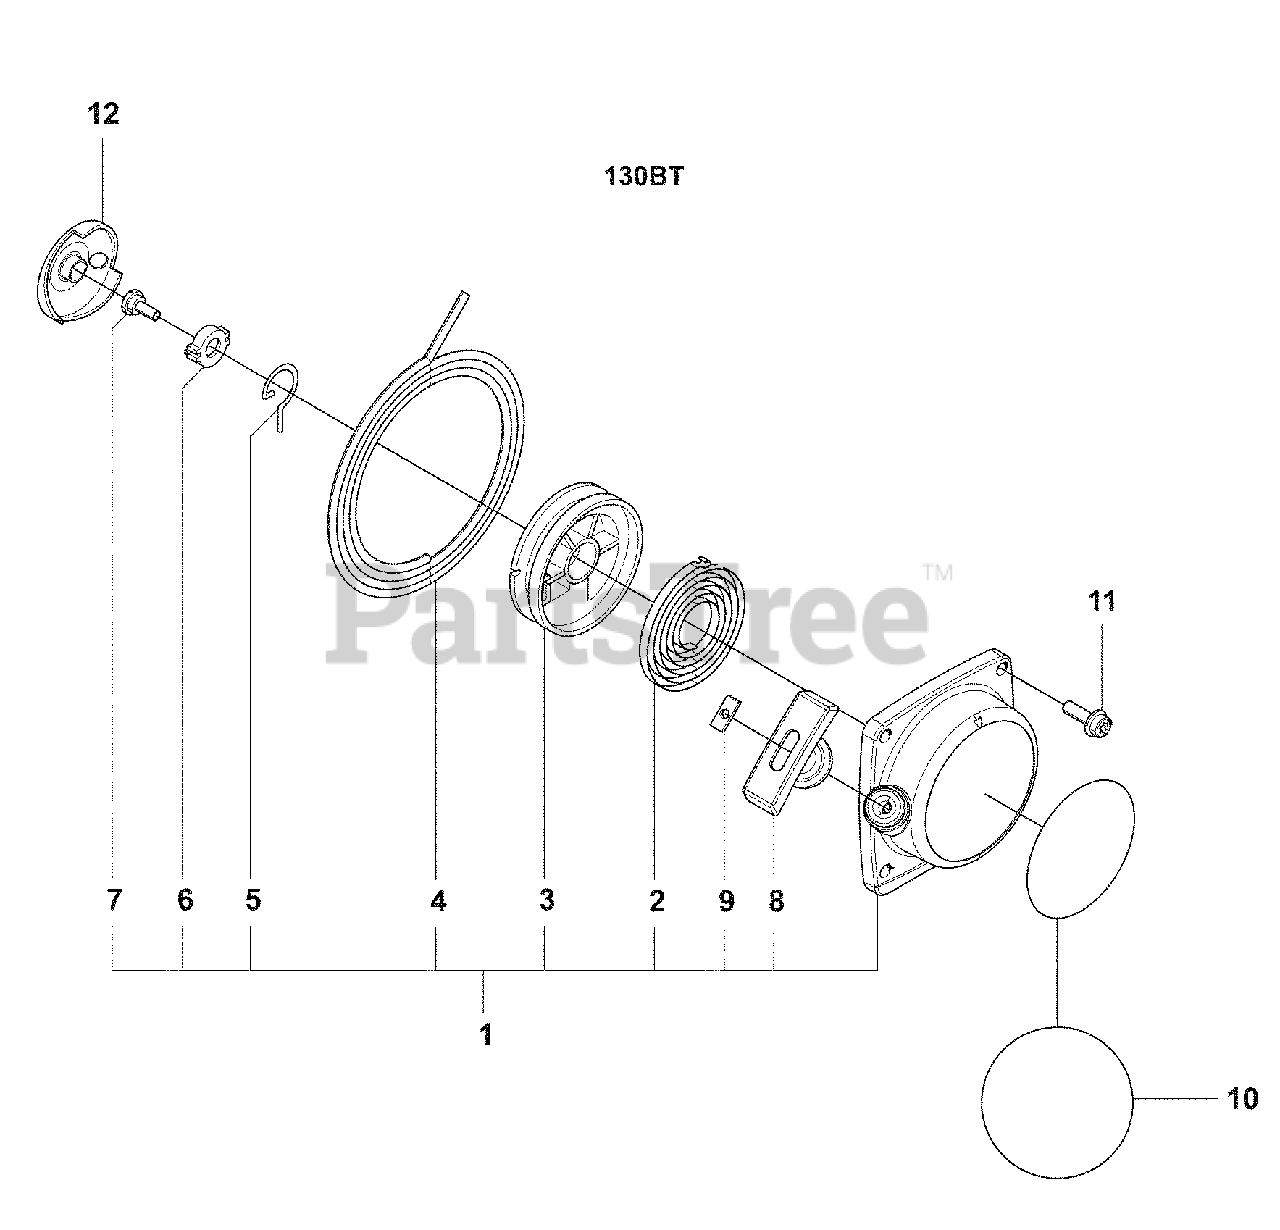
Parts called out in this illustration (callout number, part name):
1	Recoil Assembly
2	Spiral Spring
3	Spiral Spring
4	Starter Rope
7	Collar
8	Screw
10	Recoil Label
11	Bolt
